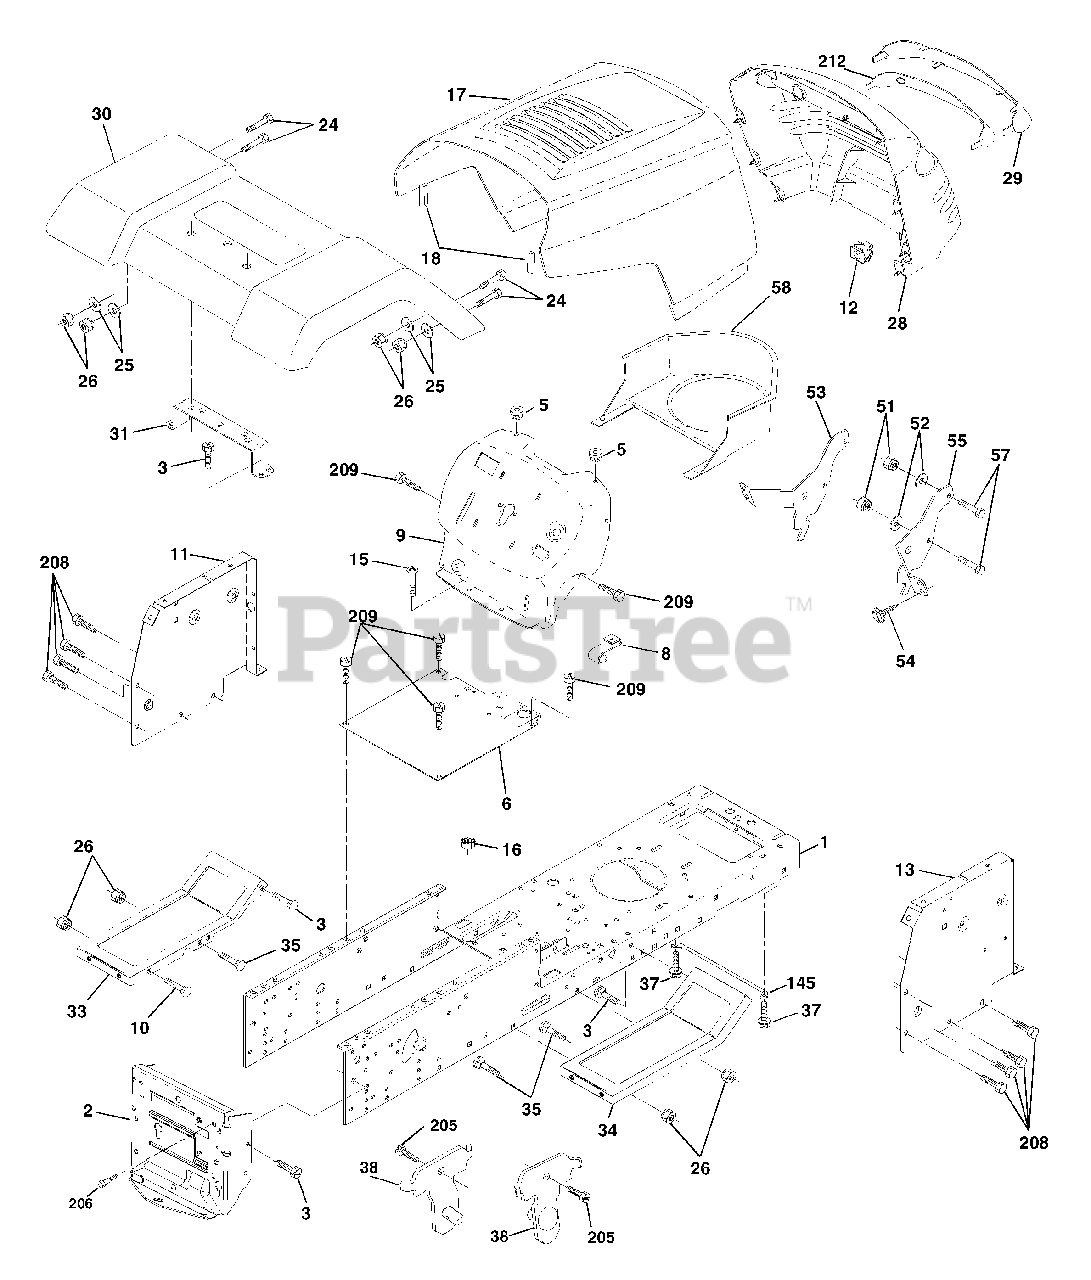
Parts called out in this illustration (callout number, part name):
1	Chassis
2	Drawbar
3	Screw 3/8-16 x 3/4
5	Bumper Hood/Dash
6	Saddle Slkscr Flat Lt 6 Sp
8	Clip Retainer Slide-On
9	Dash
10	Bolt Rd Hd Sqnk. 3/8-16 Unc x 1
11	Panel Asm. Dash Lh
12	Clip Tinnerman Grile P/L
15	Screw Mach Trhd 5/16-18 Unc x 3/4
16	Nut Keps 5/16-18 Unc
17	Hood
18	Bumper Hood
24	Bolt Fin Hex 3/8-16 Unc x 1 Gr. 5
25	Washer 13/32 x 13/16 x 12 Ga.
26	Nut Lock Hex w/Insert 3/8-16 UNC
28	Grill/Lens Asm
29	Lens Grille Private label
30	Fender Asm
31	Bracket Fender
33	Footrest
34	Footrest
35	Bolt Rd Hd Sht. Sqnk. 3/8-16 x 3/4
37	Screw Thdrol 5/16-18 x 1/2 Tyt
38	Bracket Asm. Pivot Mower Rear
51	Nut Lock Hex W/Ins. 1/4-20
52	Washer 9/32 x 7/8 x 16 Ga.
53	Bracket Grille LH
54	Screw Hex Wshd 8-18 x 7/8
55	Bracket, Grille RH
57	Bolt Fin Hex 1/4-20 x .75
58	Air Duct Private Label
145	Rod Pivot Chassis/Hood
205	Screw Thdrol 3/8-16 x 1/2
206	Bolt shoulder 5/16-18
208	Screw Thdrol 3/8-16 x 1/2
209	Screw Hex Wsh Thdrol 3/8-16
212	Insert Lens Reflector
